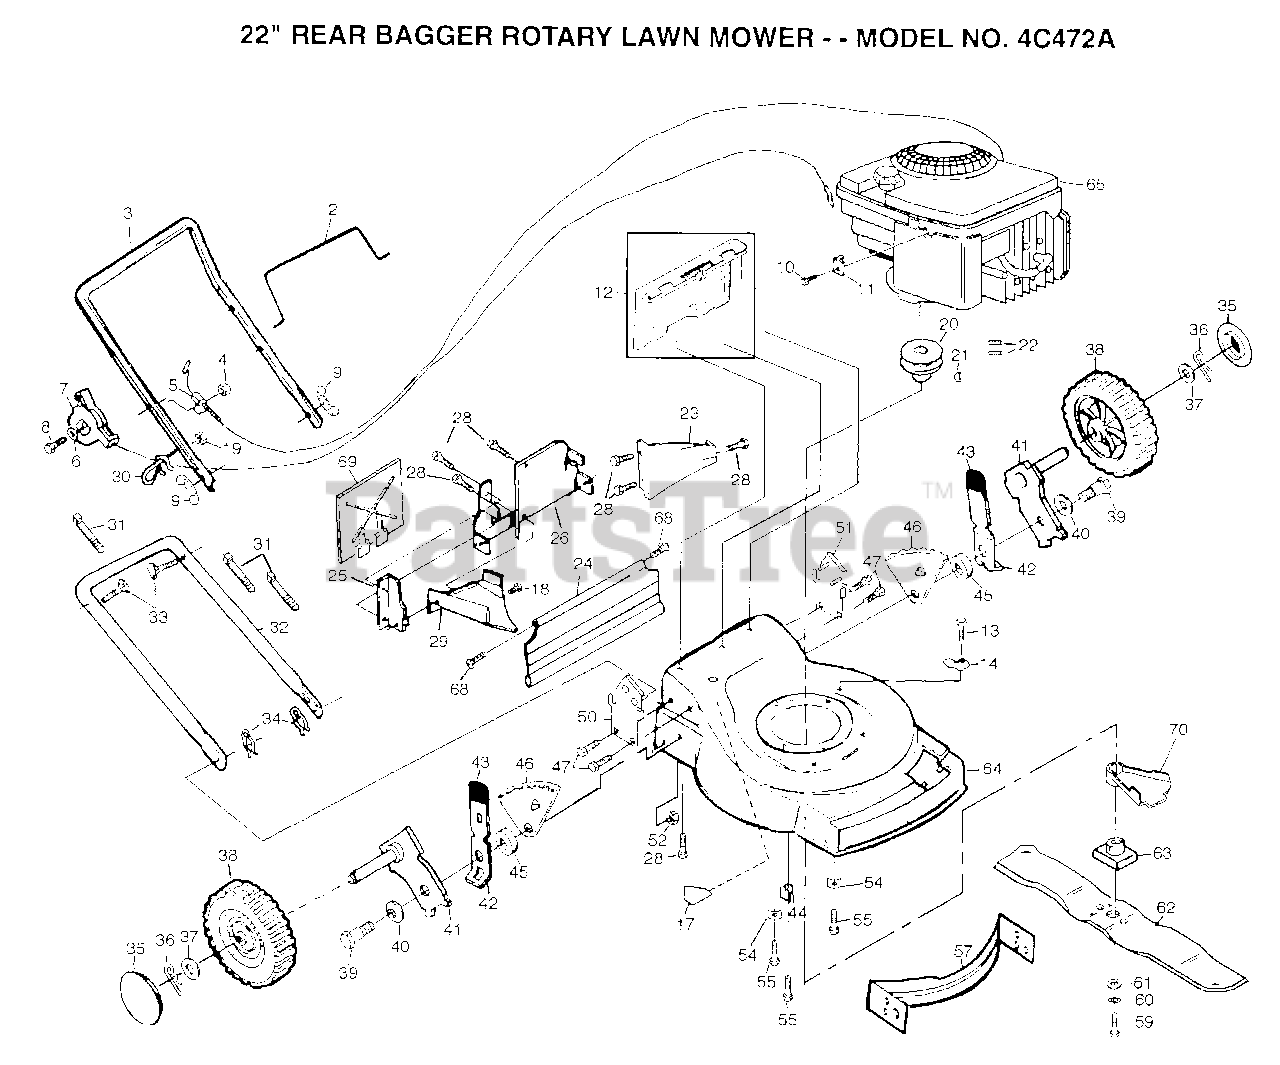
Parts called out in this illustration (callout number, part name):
2	CONTROL BAR
5	"CABLE,ENG ZONE CO"
6	WASHER PM
7	CONTROL THROTTLE
9	"NUT,WING PM"
10	SCREW PM
11	CABLE CLAMP
13	TAPPING SCREW
14	GUIDE CLIP PM
17	DECAL HYT
18	SCREW PM
19	NUT
20	ENGINE.PULLEY.FWG
21	HI PRO KEY PM
22	SCREW
23	REAR BAFFLE
26	PLATE.BACK.22RD
28	SCREW
29	DISCHARGE BAFFLE
30	ROPE GUIDE
33	BOLT.HANDLE.LM
34	HAIRPIN COTTER
35	HUB CAP
36	RETAINER CLIP PM
37	WASHER
40	"WASHER, BELLEVIL."
41	AXLE ARM
42	SPRING SELECTOR
43	KNOB PM
44	DEBRIS SHLD RET
47	SCREW
52	LOCKNUT PM
55	SCREW
59	SCREW
60	LOCKWASHER
61	"WASHER,HARDEN"
63	ADAPTOR.BLADE.LM
64	KIT.HSG.22RD.FWGD
68	HINGE SCREW
69	MULCHER PLATE
